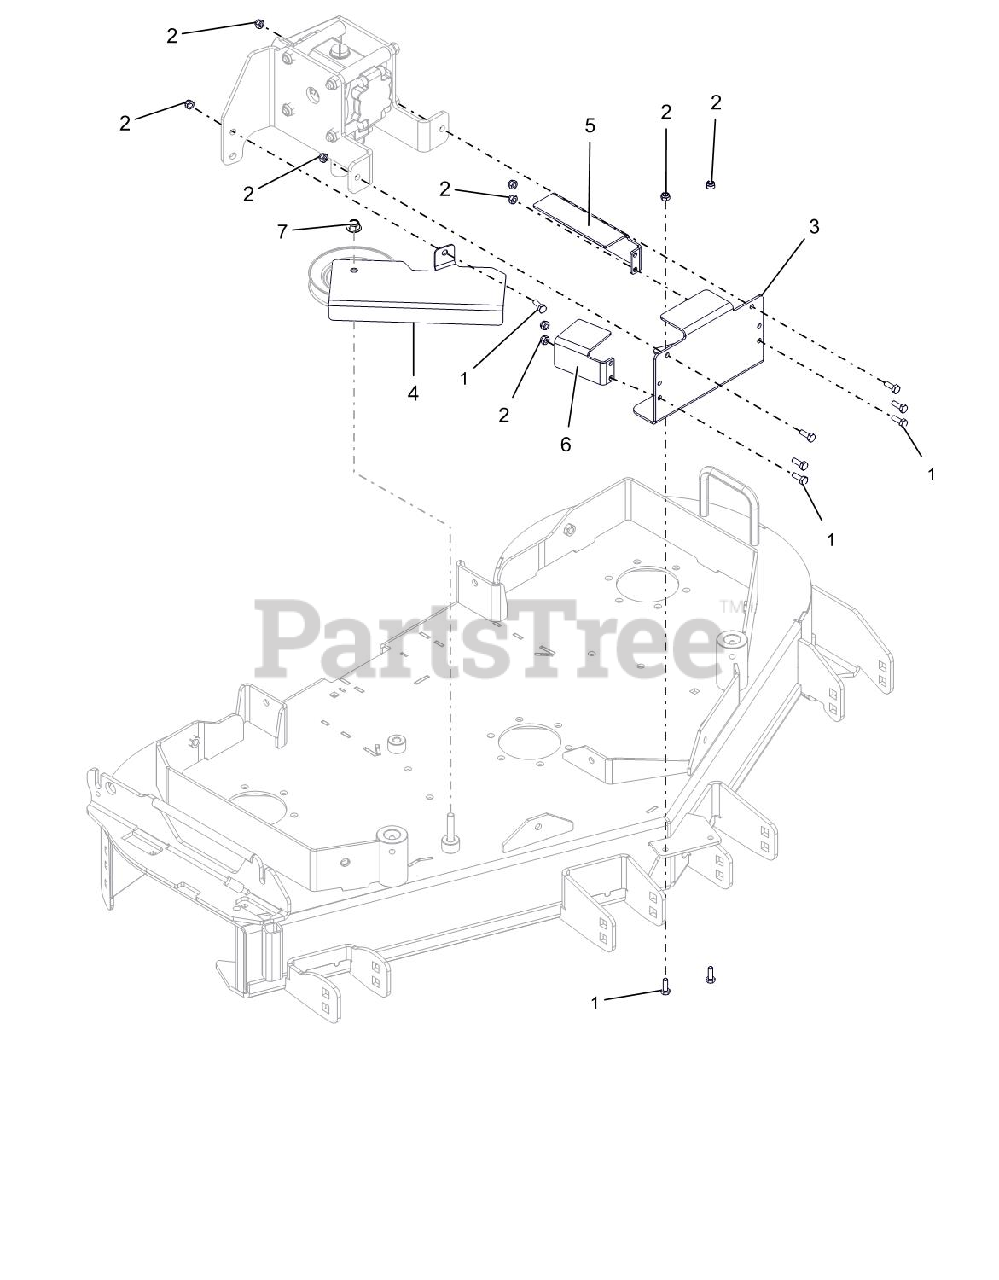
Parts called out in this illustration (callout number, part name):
1	BLT, HEX .25-20X.75 GR5 ZC120
2	NUT,NYL .25-20 G5 ZCC
3	COVER, LOWER
4	COVER, RH - 48
5	SHIELD, BELT LH
6	SHIELD, BELT RH
7	NUT,LK-NYL-FLG .38-16 G5ZC120
